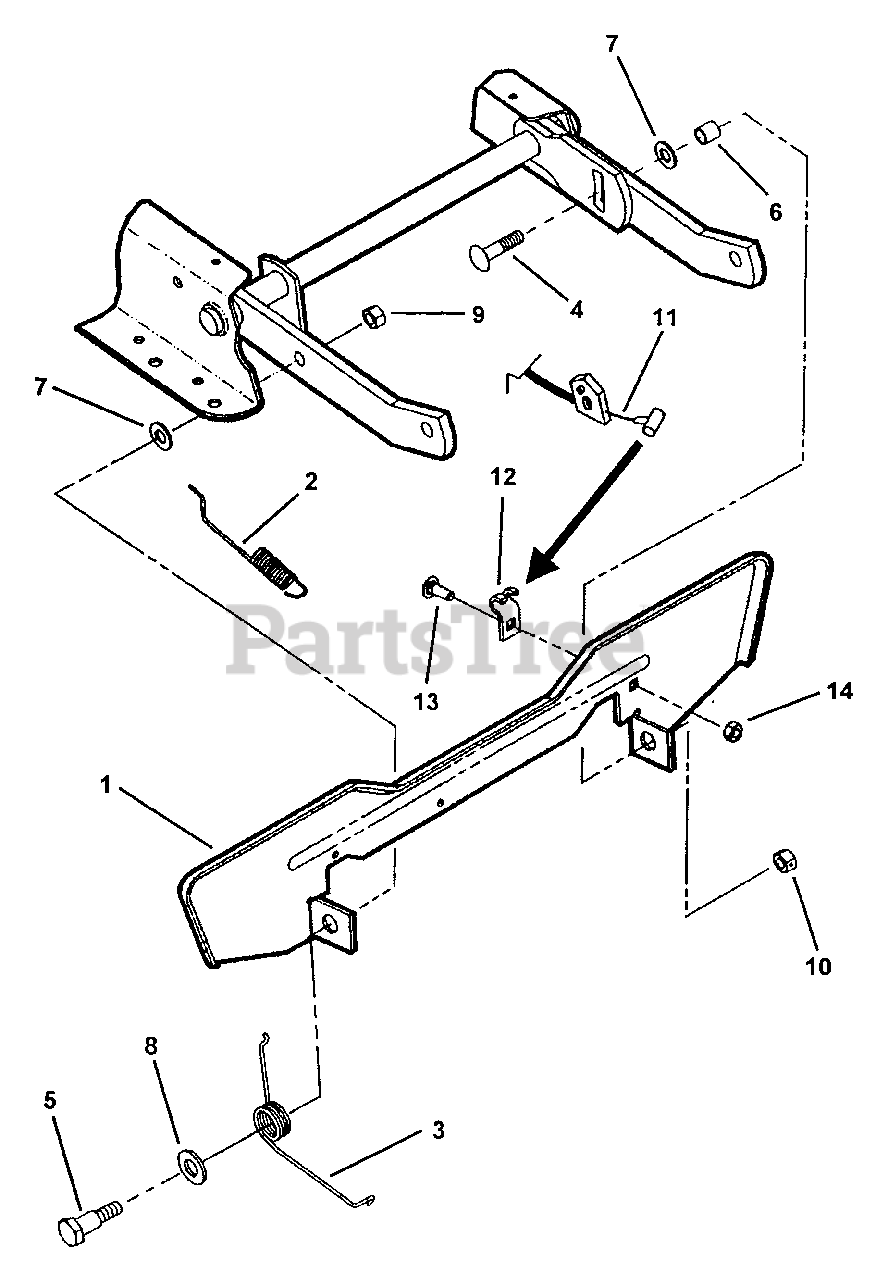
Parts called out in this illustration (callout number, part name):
1	PEDAL, Blade Stop Control
2	SPRING, Latching
3	SPRING, Pedal
4	BOLT, 3/8-16 x 1-1/2 Short Neck Carriage, Grade 5
5	BOLT, 3/8-24 x 9/16" Shoulder
7	WASHER, 3/8" Flat
8	WASHER, 1/2" Flat
9	NUT, 3/8-24 Hex Center Lock
10	NUT, 3/8-16 Hex Center Lock
11	CABLE, No Reverse In Mow
12	CLIP, Cable
13	BOLT, 1/4-20 x 3/4" Square Neck Carriage, Grade 5
14	NUT, 1/4-20 Hex, Grade 5 or B
